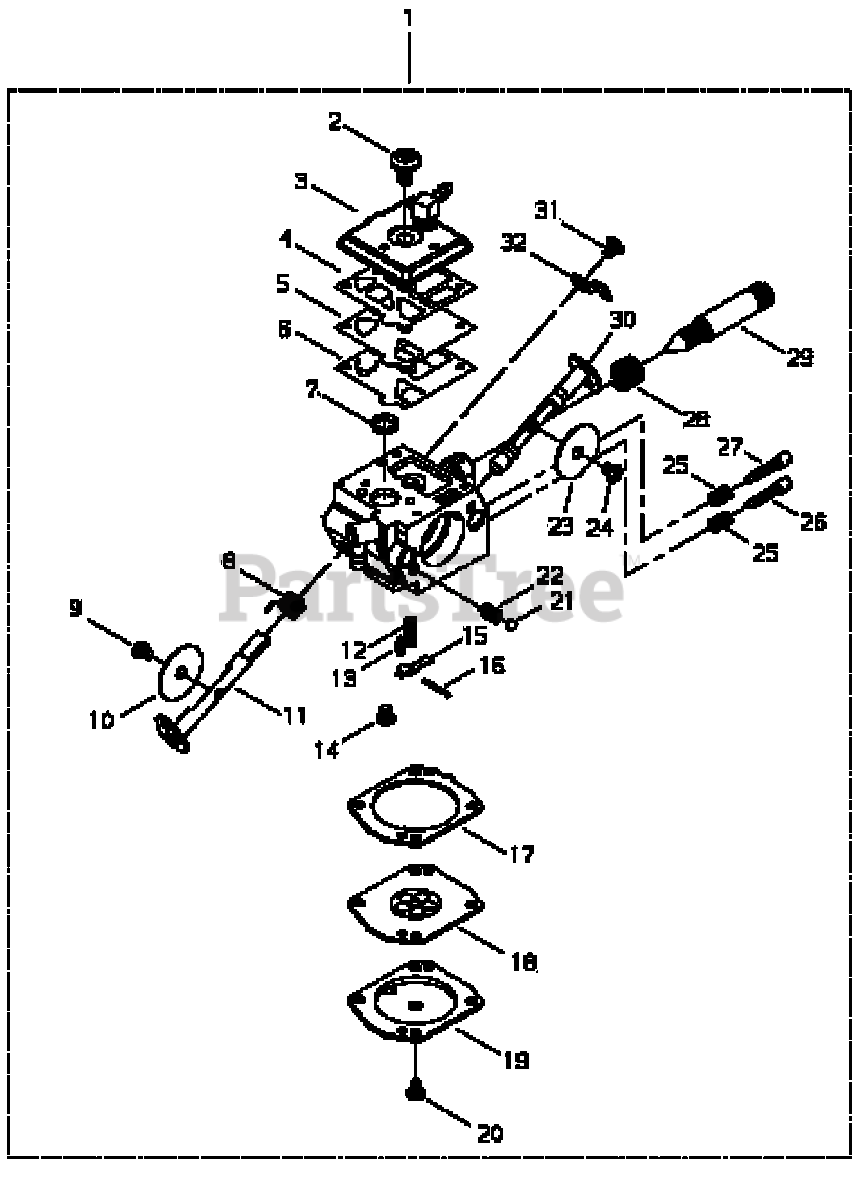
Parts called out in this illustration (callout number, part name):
1	CARBURETOR HDA-79C
2	SCREW, PUMP COVER
3	PUMP COVER ASSY
4	GASKET, PUMP
5	DIAPHRAGM, PUMP
6	DIAPHRAGM, PUMP
7	STRAINER
8	SPRING, THROTTLE RETURN
9	SCREW
10	VALVE, THROTTLE
11	SHAFT ASSY
12	SPRING, METERING LEVER
13	VALVE, INLET NEEDLE
14	SCREW, METERING LEVER PIN
15	LEVER, METERING
16	PIN, METERING LEVER
17	GASKET, METERING
18	DIAPHRAGM, METERING
19	COVER, METERING
20	SCREW
21	BALL, CHOKE
22	SPRING
23	VALVE, CHOKE
24	SCREW
25	SPRING
26	NEEDLE - HIGH SPEED
27	NEEDLE - LOW SPEED
28	SPRING, IDLE ADJUST
29	SCREW, IDLE ADJUST
30	SHAFT ASSY
31	SCREW
32	STOP, THROTTLE
